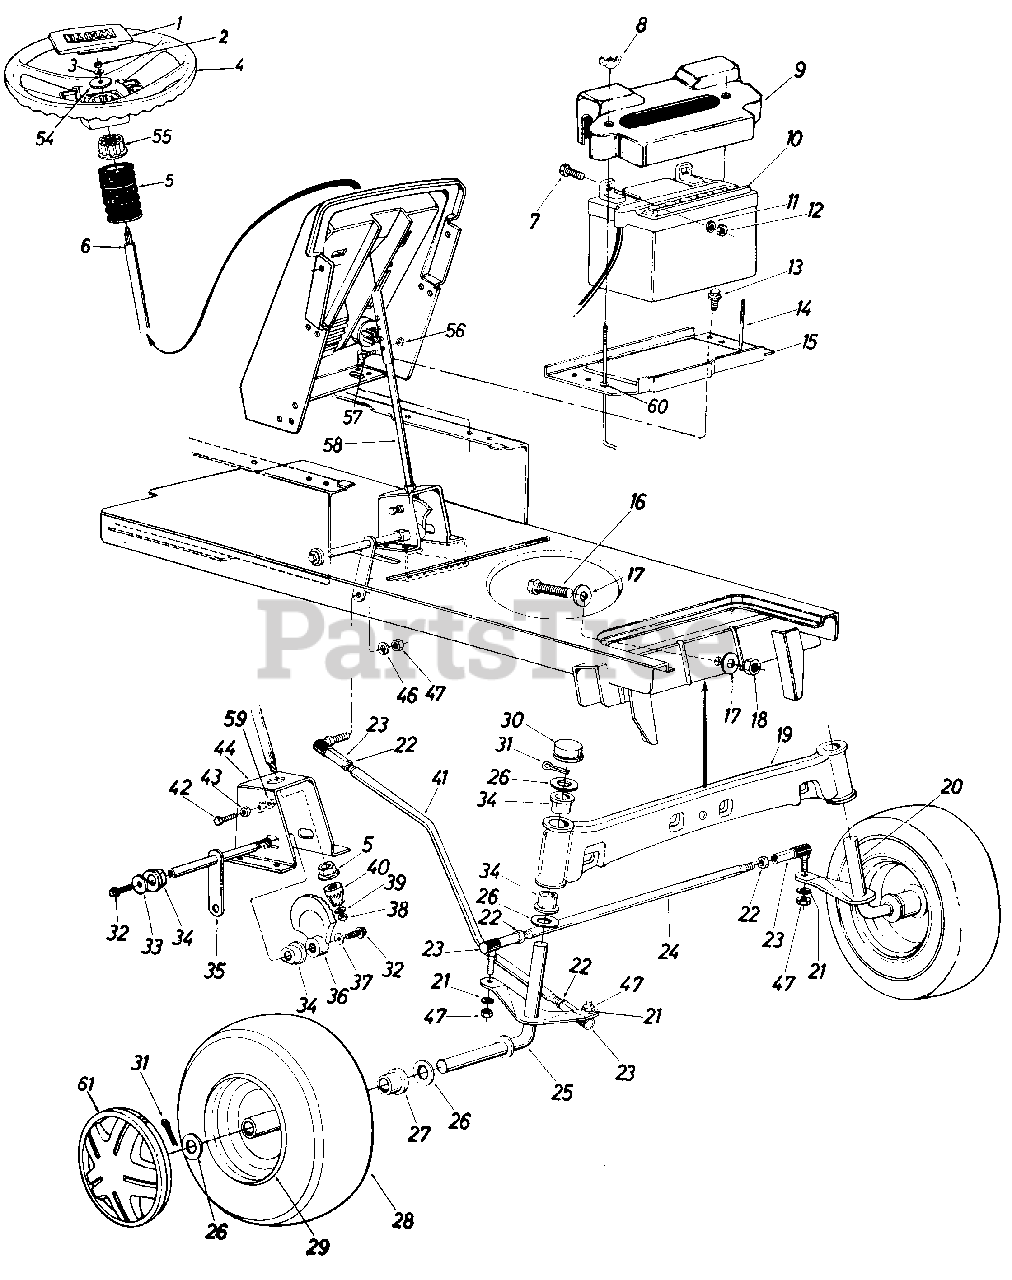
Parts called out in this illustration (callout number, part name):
1	Steering Wheel Insert
2	Hex Cent. L-Nut 5/16-24 Thd.
3	Bell-Wash. 5/16" I.D. x .87" O.D. x .060
4	Steering Wheel
5	Plastic Hex Bearing 5/8" I.D.
7	Hex BoJt 1/4-20 x .62" Lg.
8	Wing Nut Plastic 1/4-20 Thd.
9	Battery Cover
10	12-V Battery
11	L-Wash 1/4 " I.D.
12	Hex Nut 1/4-20 Thd.
13	Hex Thd. Rolling Scr. 1/4-20 0 x.50" Lg.
14	Battery Hold Down Rod
15	Battery Plate
16	Hex Bolt 5/8-18 x 2.5" Lg.
17	Flat Wash. .66" I.D. x 2.25" O.D. x .17
18	Hex Cent. L-Nut 5/8-18 Thd.
19	Front Pivot Bar Ass'y.
20	Front Axle Ass'y.-L.H.
21	L-Wash. 3/8" I.D.
22	Hex Jam Nut 3/8-24 Thd.
23	Ball Joint Ass'y.
25	Front Axle Ass'y.-R.H.
26	Fl-Wash. .780 I.D. x 1.59 O.D.
27	Flange Bearing
28	Front Wheel Ass'y. Comp.
29	Front Wheel Rim Only
30	Dust Cover
31	Cotter Pin 5/32" Dia. x 1.00" Lg.
32	Hex Bolt 3/8-24 x .75" Lg. Grade 5
33	Fl-Wash. 3/8 I.D. x 1.25 O.D. x .090
34	Flange Double "D" Brg. .753 0 I.D.
35	Steering Arm Shaft Ass'y.
36	Side Gear-Steering
37	Bell-Wash. 3/8" I.D.
38	Hex Cent. L-Nut 5/16-24 Thd.
39	Fl-Wash. 5/16" I.D. x .62 O.D. x .059
40	Pinion Gear-Steering
42	Hex Bolt 3/8-16 x 1.25" Lg.
43	Hex Nut 3/8-16 Thd.
44	Steering Gear Sup. Ass'y.
46	L-Wash. 3/8" I.D.
47	Hex Nut 3/8-24 Thd.
54	Fl-Washer
55	Steering Wheel Adapter
56	Hex L-Nut 1/4-20 Thd.
57	Hex Bolt 1/4-20 x 1.25" Lg.
58	Lower Steering Shaft
60	Push Nut
